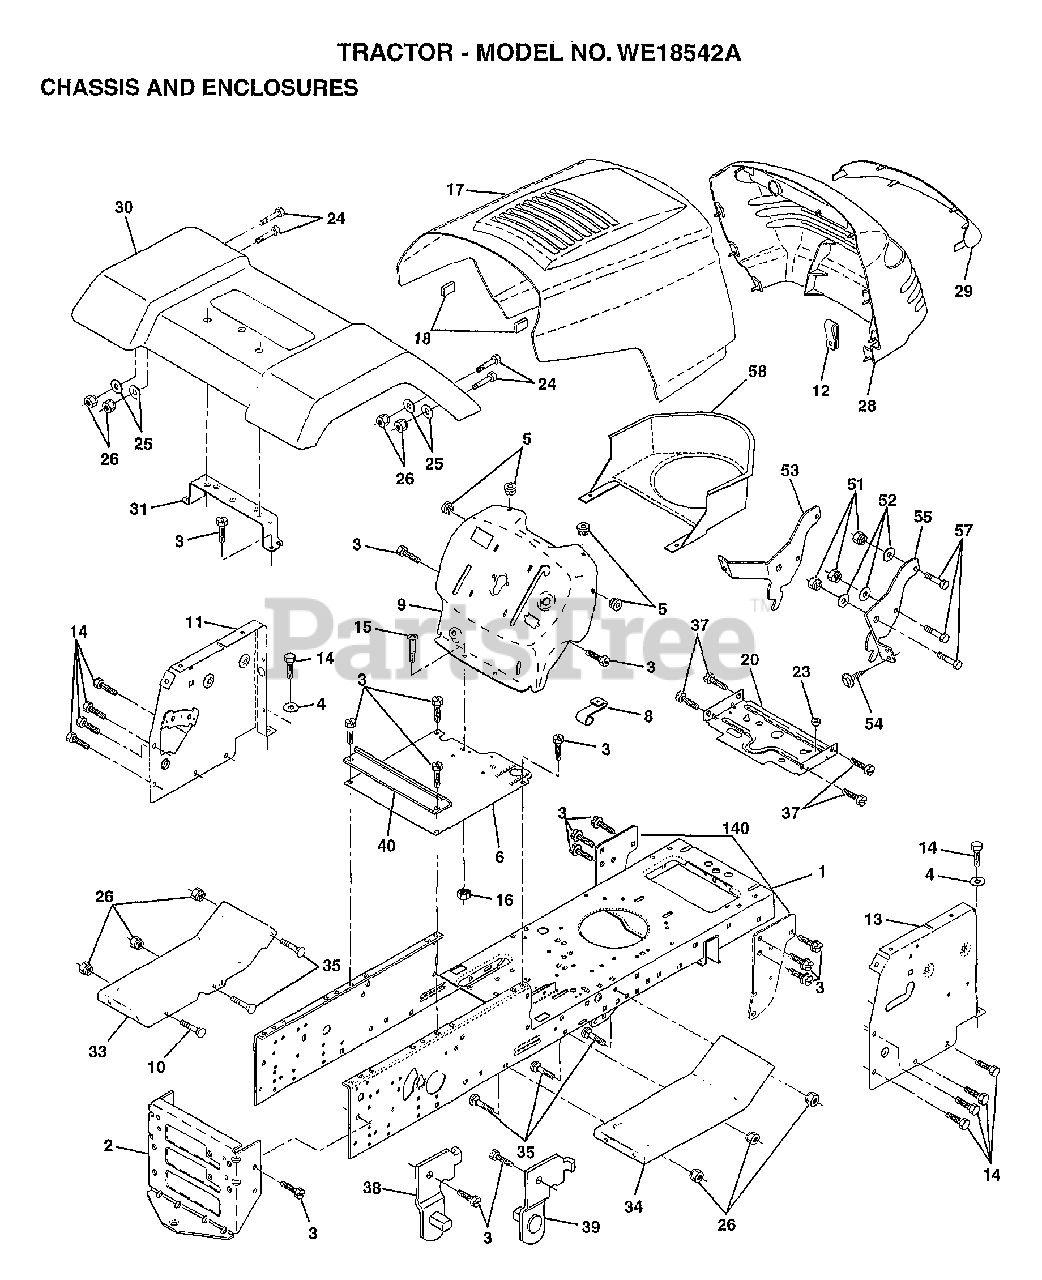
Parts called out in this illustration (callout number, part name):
1	CHASSIS ASM
3	SCREW
4	WASHER
5	BUMPER-HOOD/DASH
6	SADDLE
8	CLIP.RETAINER
9	DASH.SILKSCREENED
11	"PANEL-DASH,LH"
12	CLIP.TINNERMAN
14	SCREW LT
15	SCREW
20	"PLATE-MTG,BATT/FU"
24	BOLT
25	WASHER
26	NUT
28	GRILLE-MS428
29	LENS GRILLE
30	FENDER
31	BRACKET SUPT FEND
33	FOOTREST.LH.LT/GT
34	FOOTREST.RH.LT/GT
35	BOLT
37	SCREW LT
38	BRACKET ASM LH
39	BRACKET ASM RH
40	SPACER FENDER LT
51	NUT
52	WASHER
53	BRACKET.GRILLE.LH
55	BRACKET.GRILLE.RH
58	DUCT.AIR.B&S.18HP
140	BRKT SUSPENSION
